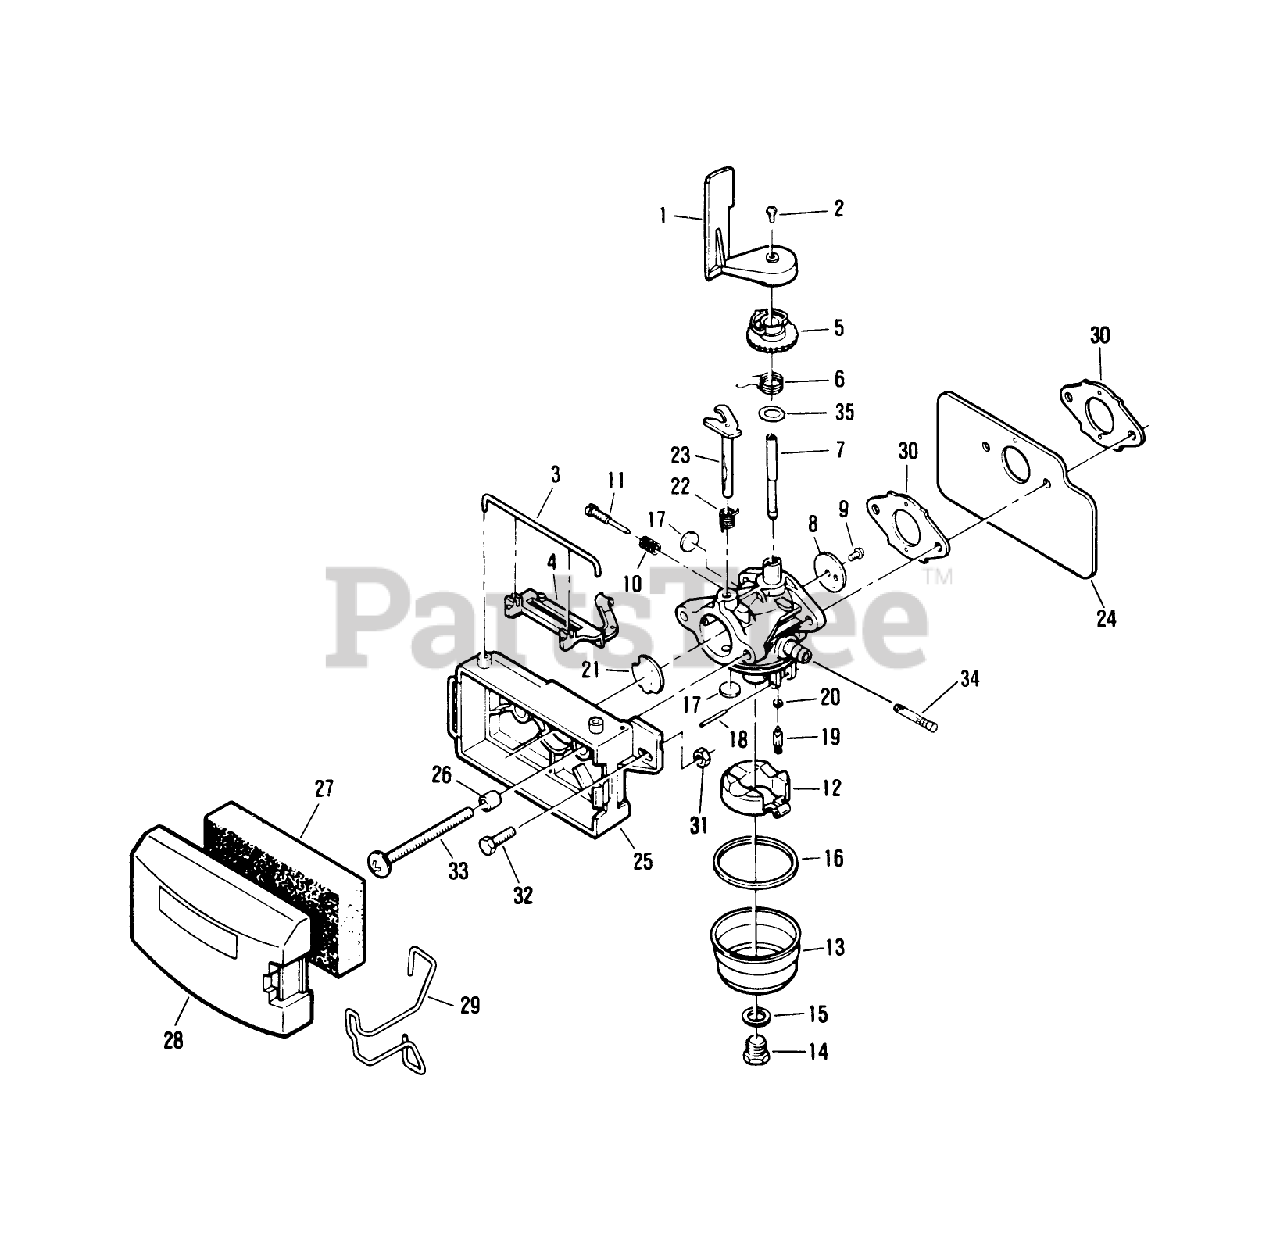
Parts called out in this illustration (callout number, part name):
1	AIR VANE F
2	SCREW F
3	RETAINER
5	COLLAR A/VAVE F
6	THROTTLE SPR E
7	Shaft-Throttle
8	Valve-Throttle
9	Screw-Throttle Valve
10	Spring-Idle Needle
11	Needle-Idle
13	Bowl-Fuel
14	Screw-Bowl Retainer
15	Gasket-Bowl Retainer
16	Gasket-Fuel Bowl
17	Plug-Welch
18	Shaft-Float
19	Valve-Inlet Needle
20	Seat-Valve
21	Valve-Choke
22	Spring-Choke Return
23	Shaft-Choke
26	SPACER
29	RETAINER-COVER, FILTER
30	GASKET CARB S
32	SCREW
33	SCREW
34	SCREEN FUEL PITTS
35	WASHER VF
